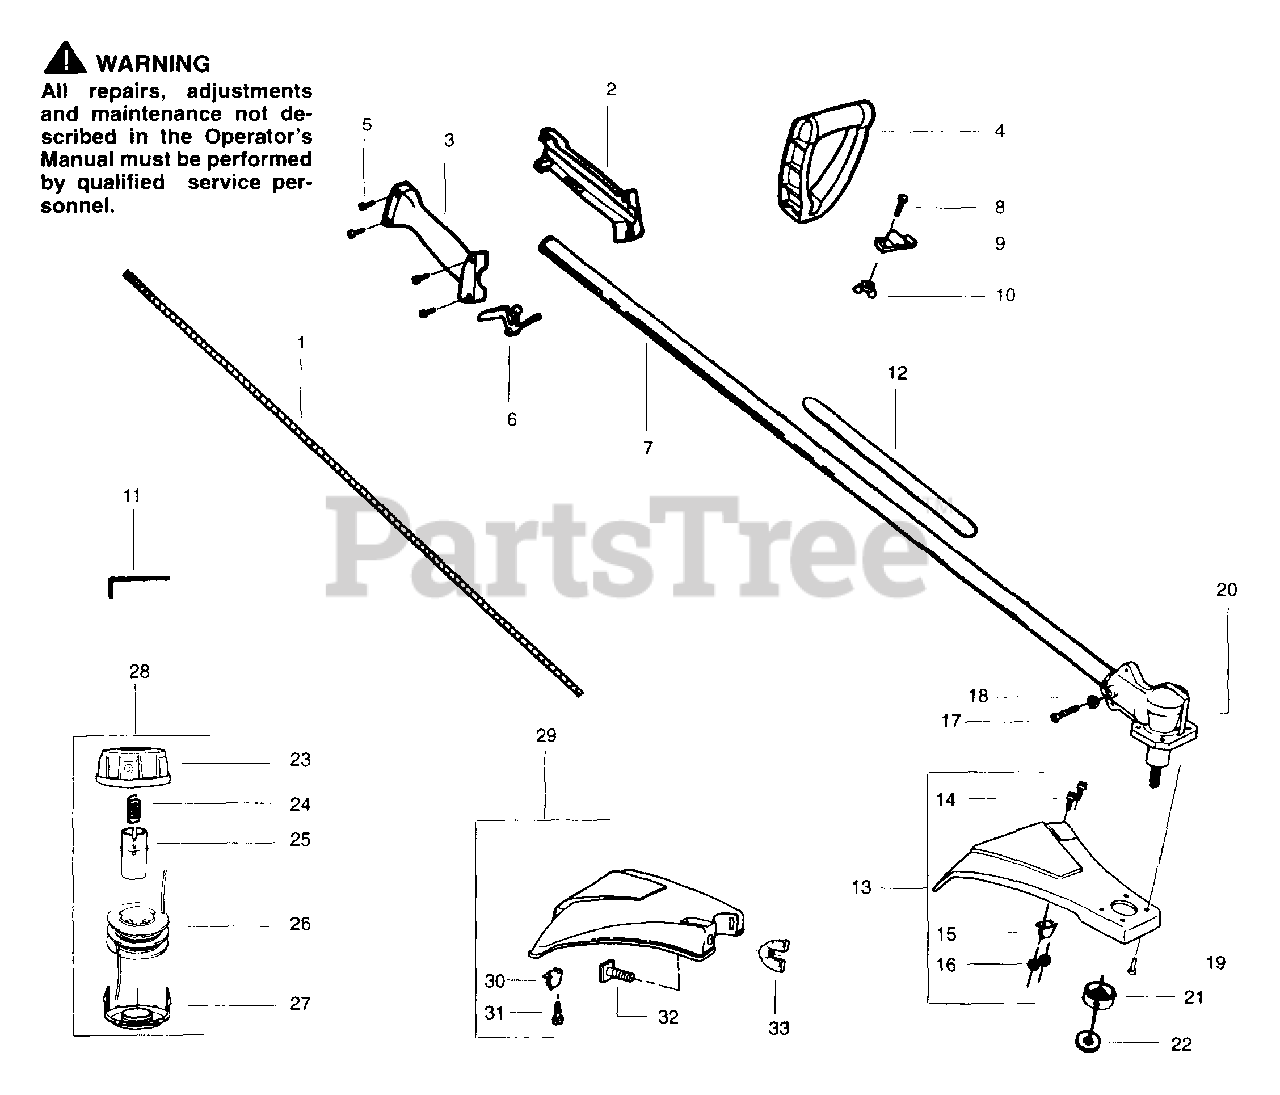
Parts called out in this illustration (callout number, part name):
1	Drive Shaft - 52"
2	Throttle Hsg (Left)
3	Throttle Hsg (Right)
4	Handle Ass'y
5	Screw - Throttle Hsg
6	Throttle Lever
7	Drive Shaft Hsg Ass'y
10	Wingnut
11	Hex Wrench 5/32
12	Shaft Warning Decal
13	Shield Kit Ass'y - Metal Shield
14	Screw - Line Limiter
15	Line Limiter
16	Locknut - Line Limiter
17	Screw - Gear Box
18	Lockwasher - Gear Box
19	Screw - Gear Box/Shield
20	Gear Box Ass'y
21	Dust Cup
22	Grass Washer
23	Hub Ass'y
25	Release Button
26	Spool w/Line
28	Cutting Head Ass'y
29	Shield Kit Ass'y - Plastic Shield
30	Line Limiter
30	Line Limiter - 17"
30	Line Limiter - 18"
31	Screw
33	Wing Nut
